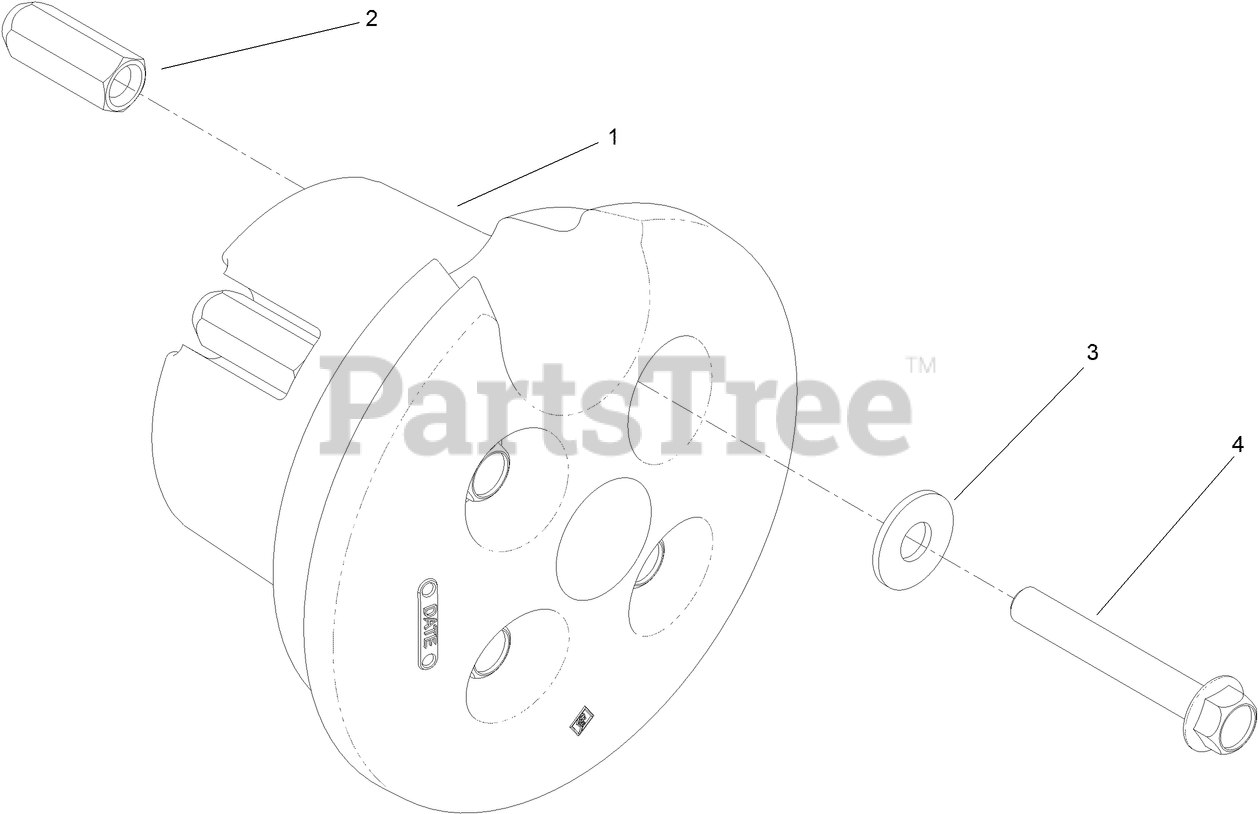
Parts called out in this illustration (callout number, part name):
1	WEIGHT-WHEEL
2	ADAPTOR-NUT, WHEEL
3	WASHER-FLAT
4	SCREW-HHF
